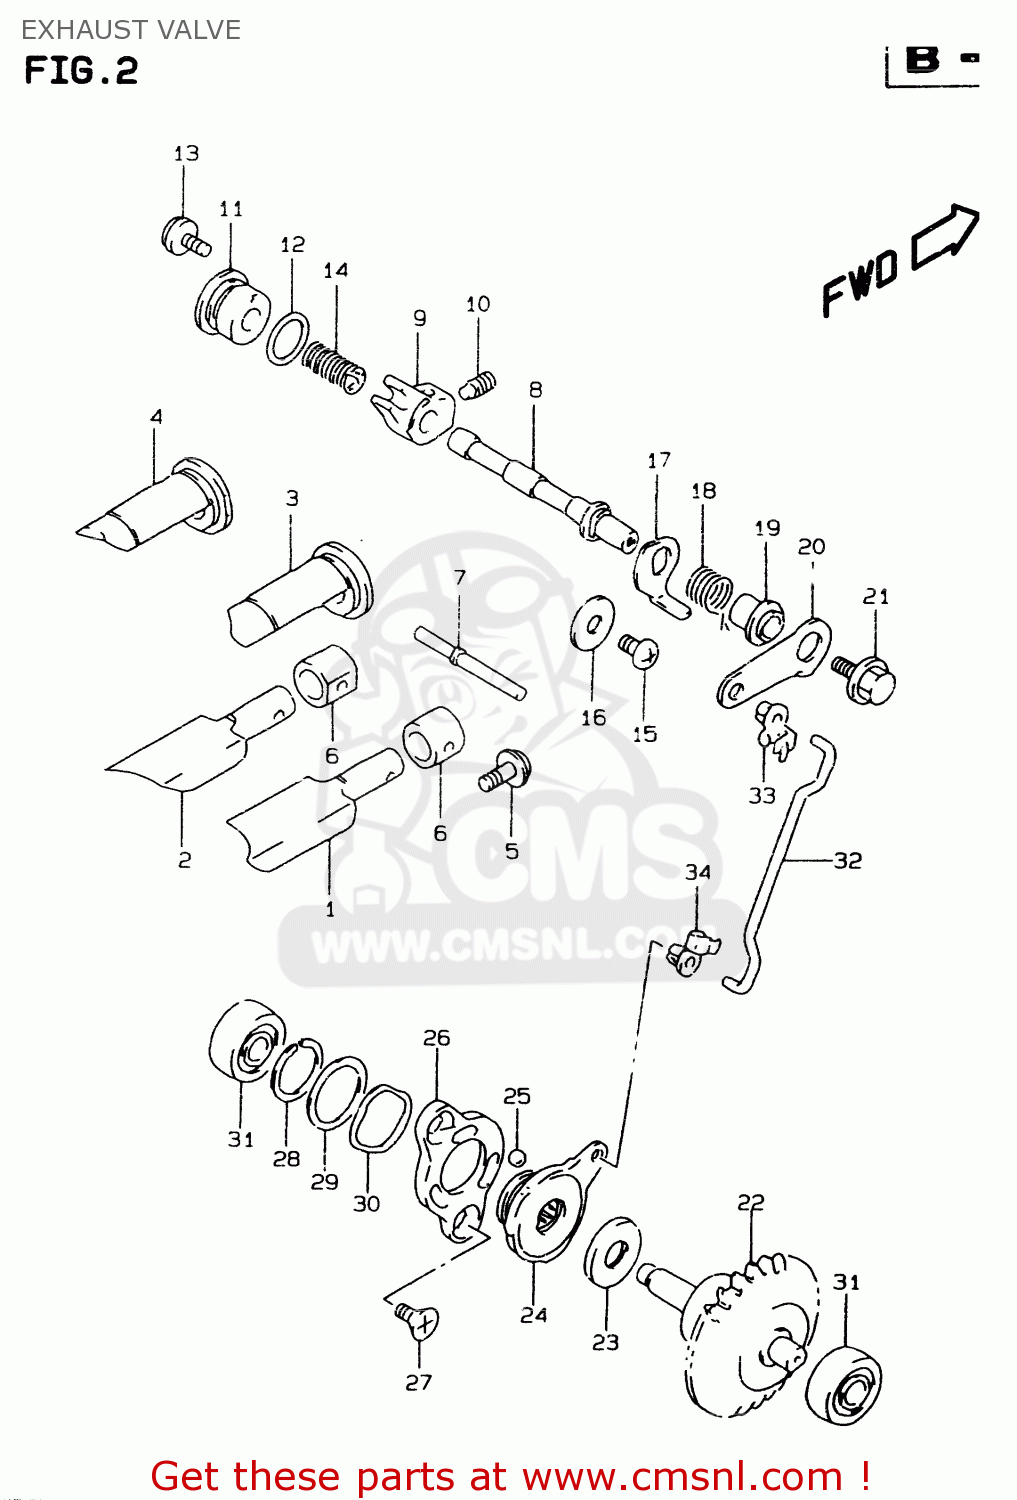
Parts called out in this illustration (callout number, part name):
1	VALVE,EXHAUST,R
2	VALVE,EXHAUST,L
3	GUIDE,EXHAUST VALVE,R
4	GUIDE,EXHAUST VALVE,L
5	SCREW 5X12
6	SPACER,EXHAUST VALVE
7	PIN,EXHAUST VALVE 48.5MM
8	SHAFT,EXHAUST VALVE
9	ARM,EXHAUST VALVE SHAFT
10	SCREW(6X10)
11	CAP,EXHAUST VALVE
12	O RING(D:1.9,ID:14.5)
13	BOLT
14	SPRING
15	SCREW
16	WASHER
17	LEVER,EXHAUST VALVE NO.2
18	SPRING
19	SPACER,EXHAUST VALVE
20	LEVER,EXHAUST VALVE NO.1
21	BOLT(5X12)
22	GOVERNOR ASSEMBLY,EXHAUST
23	BEARING(10X22X2.8)
24	ACTUATOR,EXHAUST VALVE
25	BALL
26	STARTER,EXHAUST VALVE ACTUATOR
27	SCREW(5X10)
28	CIRCLIP
29	SHIM(19.1X25X0.3)
30	WASHER
31	BEARING(8X22X7)
32	ROD,EXHAUST VALVE
33	BUSH,EXHAUST VALVE ROD NO.1
34	BUSH,EXHAUST VALVE ROD NO.2
